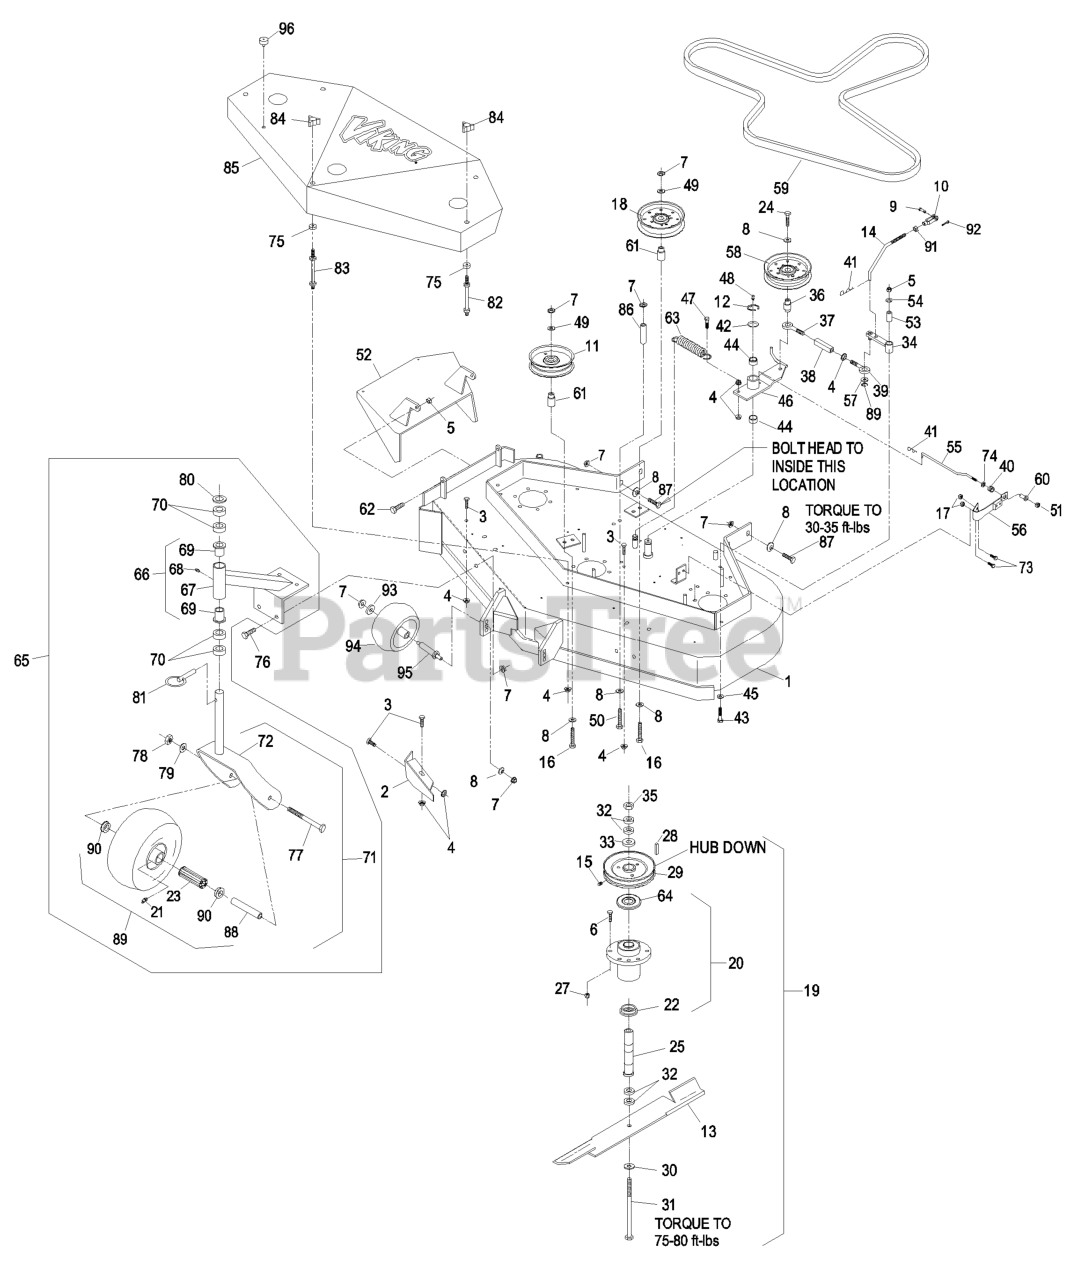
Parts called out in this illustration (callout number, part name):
1	DECK-SERVICE, 48
2	BAFFLE-DOGLEG
3	SCREW-HH
5	NUT-LOCK, NI
6	SCREW-HH
7	NUT-HHF, WHIZ
8	WASHER-BELLEVILLE
9	PIN-CLEVIS
10	YOKE-ADJUSTABLE
11	PULLEY-IDLER
12	RING-RETAINING, EXT
14	ARM-LINKAGE, ASSIST
15	SCREW-SET
16	SCREW-HH
17	NUT-LOCK, NI
21	FITTING-GREASE
22	SPACER-GUARD, BOTTOM
23	BEARING
24	SCREW-HH
25	TUBE-SPINDLE, SHORT
26	RING-RETAINING, EXT
27	NUT-LOCK, NI
29	SHEAVE
30	WASHER-SPRING
31	SCREW-CAP, HH
33	WASHER-RETAINER, SHEAVE
34	ARM-ASSIST, 32/36
35	NUT-HEX
36	BUSHING-ENGAGEMENT
37	EYEBOLT-THREAD, LH
38	BODY-TURNBUCKLE
39	EYEBOLT-THREAD, RH
40	SPRING-COMPRESSION
41	PIN-COTTER
42	WASHER-SPINDLE
43	SCREW-HH
44	SLEEVE-BEARING
45	WASHER-SPRING
46	IDLER ARM ASM
47	SCREW-HH
48	FITTING-GREASE
49	WASHER-FLAT
50	SCREW-HH
51	NUT-LOCK, NI
52	WLD,CHUTE 48
53	TUBE-PIVOT
54	WASHER-FLAT
55	ROD-BRAKE
56	PAD AND SPRING ASM
57	WASHER-PLAIN
59	BELT,BLADE 48
60	SPACER-FLANGED
62	SCREW-HH
63	SPRING-EXTENSION
64	GUARD-BEARING, TOP
66	ASM,CSTR SUPPORT W/WEIGHT
68	FITTING-GREASE
69	BEARING-FLANGED
70	SPACER-CASTER
71	ASM,CASTER/WHEEL
73	SCREW-HH
74	RING-PUSH ON
76	SCREW-HH
77	SCREW-HH
78	NUT-HH
79	WASHER-LOCK
80	WASHER-FLAT
82	STUD-SHIELD, BELT (SHORT)
83	STUD-SHIELD, BELT (LONG)
84	KNOB-3 PRONG
87	SCREW-HH
88	SPACER FRONT CASTER
89	KIT, SP CASTER WHEEL REPL
90	BUSHING, SP CASTER
91	NUT-HEX
92	PIN-COTTER
94	ROLLER-SCALP, ANTI
